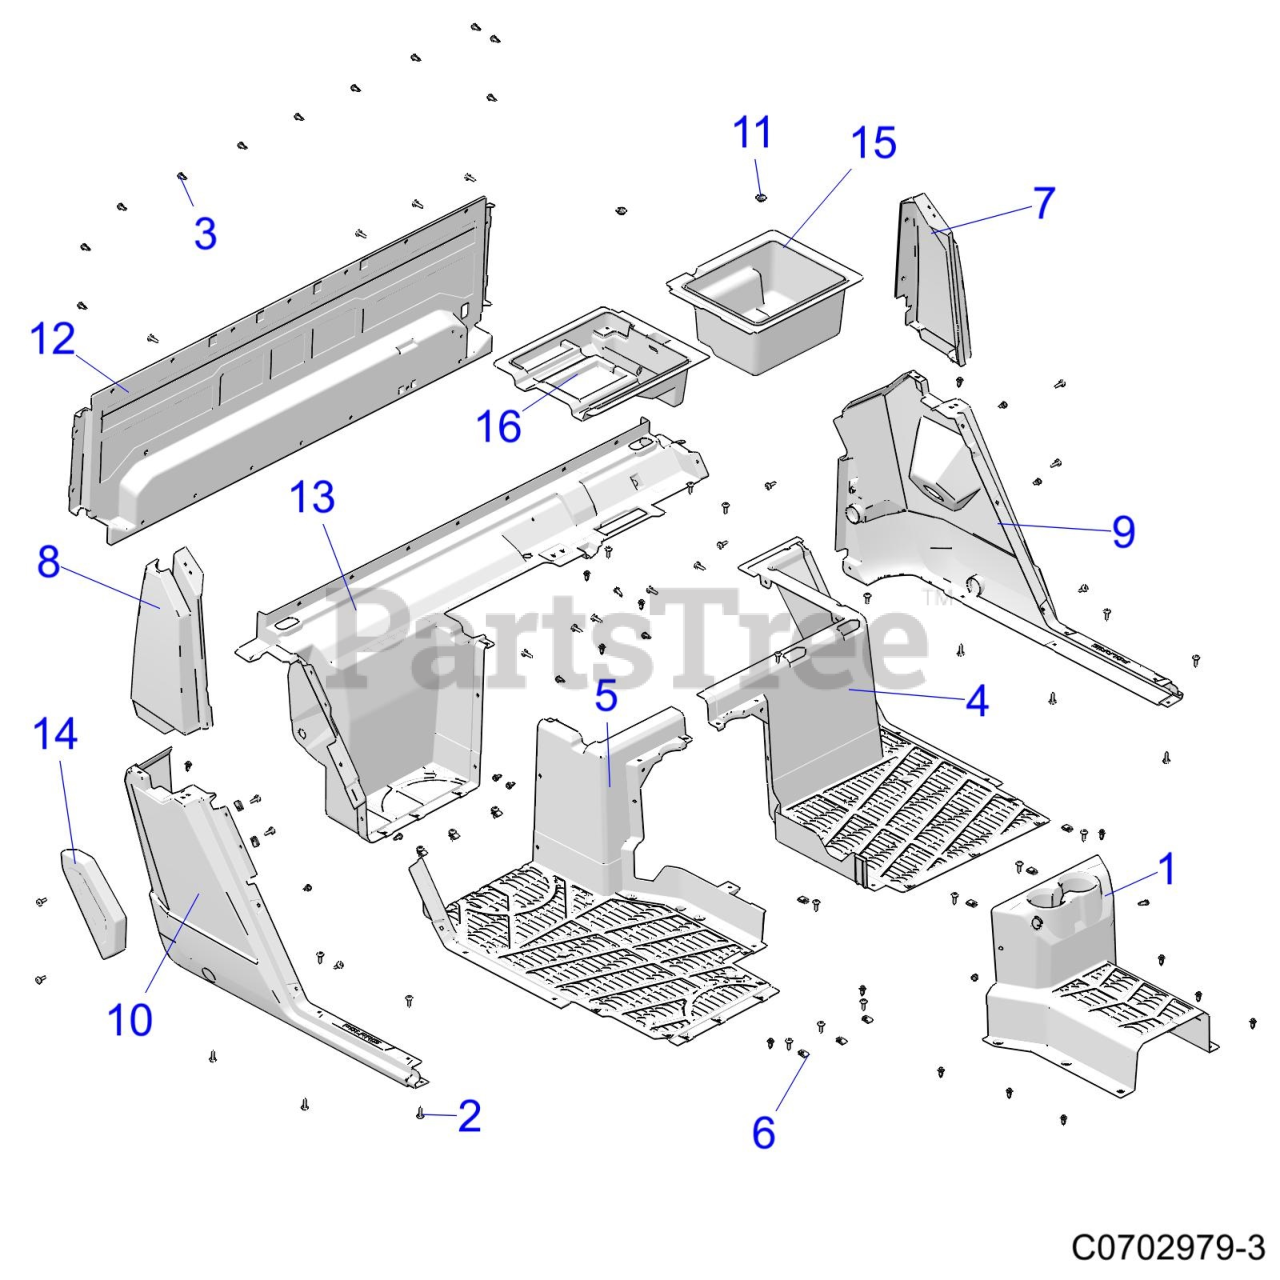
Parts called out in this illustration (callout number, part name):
1	COVER-TUNNEL FLOOR, REAR, BLK
2	SCR-TXTH-M6X1.0X25 RIE
3	RIVET-TUFLOK,.315-.325X.787 (5
4	FLOOR, REAR, LH, BLK
5	FLOOR, REAR, RH, BLK
6	NUT-M6-1.0,U-TYPE (2.5-3.8)
7	FENDER-REAR,UPPER,LH,BLK
8	FENDER-REAR,UPPER,RH,BLK
9	COVER-ROCKER,LH,BLK
10	COVER-ROCKER,RH,BLK
11	PLUG-COMPARTMENT
12	PANEL-CLOSEOFF,REAR,BLK
13	PANEL-CLOSEOFF,LOWER,BLK
14	COVER-SEAT PIVOT,BLK
15	BIN-STORAGE,LH,BLK
16	BIN-STORAGE,RH,BLK
